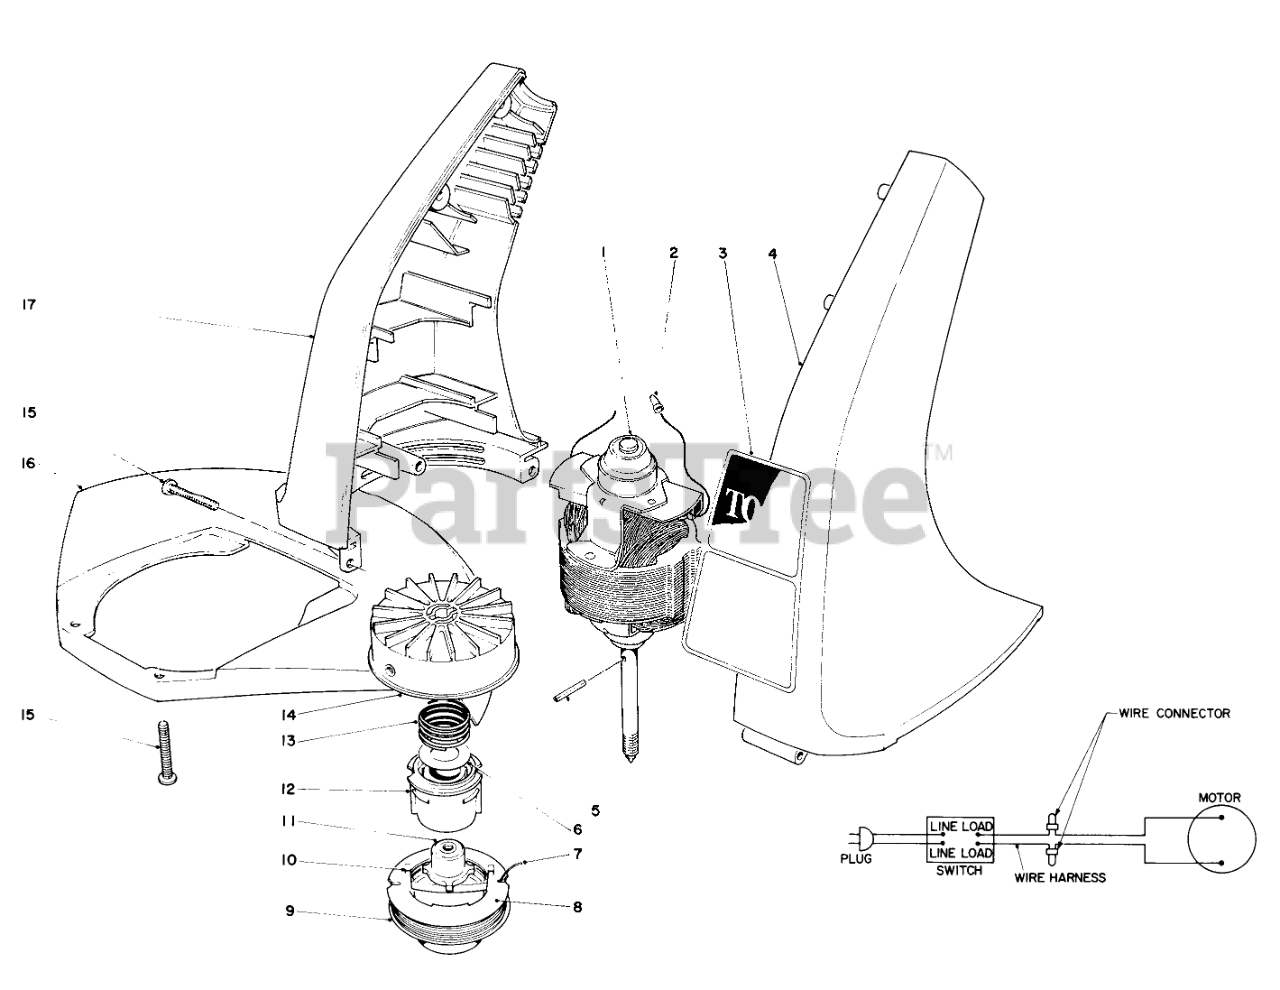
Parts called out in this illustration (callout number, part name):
1	Motor
2	CONNECTOR WIRE JOINT
3	DECAL - 1100 CANADIAN
4	Housing-Left Hand
5	COIL PIN
6	WASHER-FLAT
7	LINE-FILIMENT
8	Empty SPooI
9	Cutting Line (50 .065" Dia.)
10	SADDLE-SPOOL CAP
11	Driver
12	SPOOL CORE
13	SPRING COMPRESSION
14	DRUM W/EYELET
15	Screw
16	Shield
17	R.H. HOUSING, 1100
